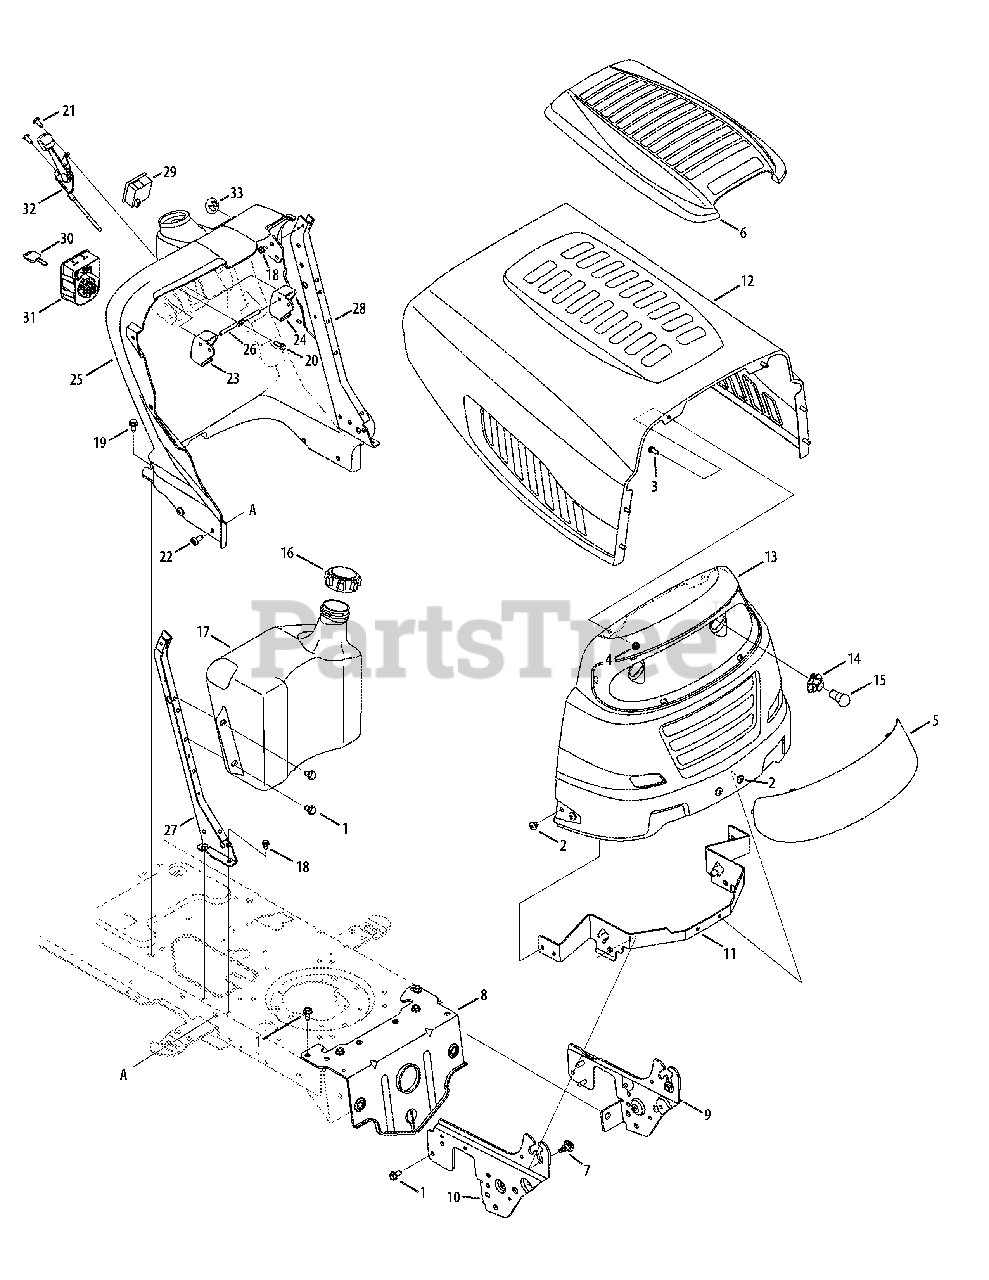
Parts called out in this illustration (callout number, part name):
1	Screw, 5/16-18 x .750
2	Screw, 5/16-18 x .375
3	Hex Cap Screw, 1/4-20 x.62
4	Flange Lock Nut, 1/4-20
5	Headlight Lens
6	Cover Hood 5-Style
7	Shoulder Screw,.43 x.29
14	Headlight Socket
15	Lamp
16	Fuel Cap
17	Fuel Tank, Two Gallon
18	Self-tapping Screw, 1/4-20 x.5
19	Screw, 5/16-18 x .500
20	Self-tapping Screw, 1/4-15 x.75
21	Screw, 1/4-14 x.625
22	Screw, 5/16-18 x.75
23	Cruise Control Button
24	Parking Brake Button
25	Dash Panel
26	Brake/Cruise Pivot Rod
29	Ammeter Monitor Indicator w/o Lts.
30	Ignition Key w/ plastic cover
30	Ignition Key w/o plastic cover
31	Ignition Switch
32	Throttle/Choke Control & Cable
33	Choke Plug
